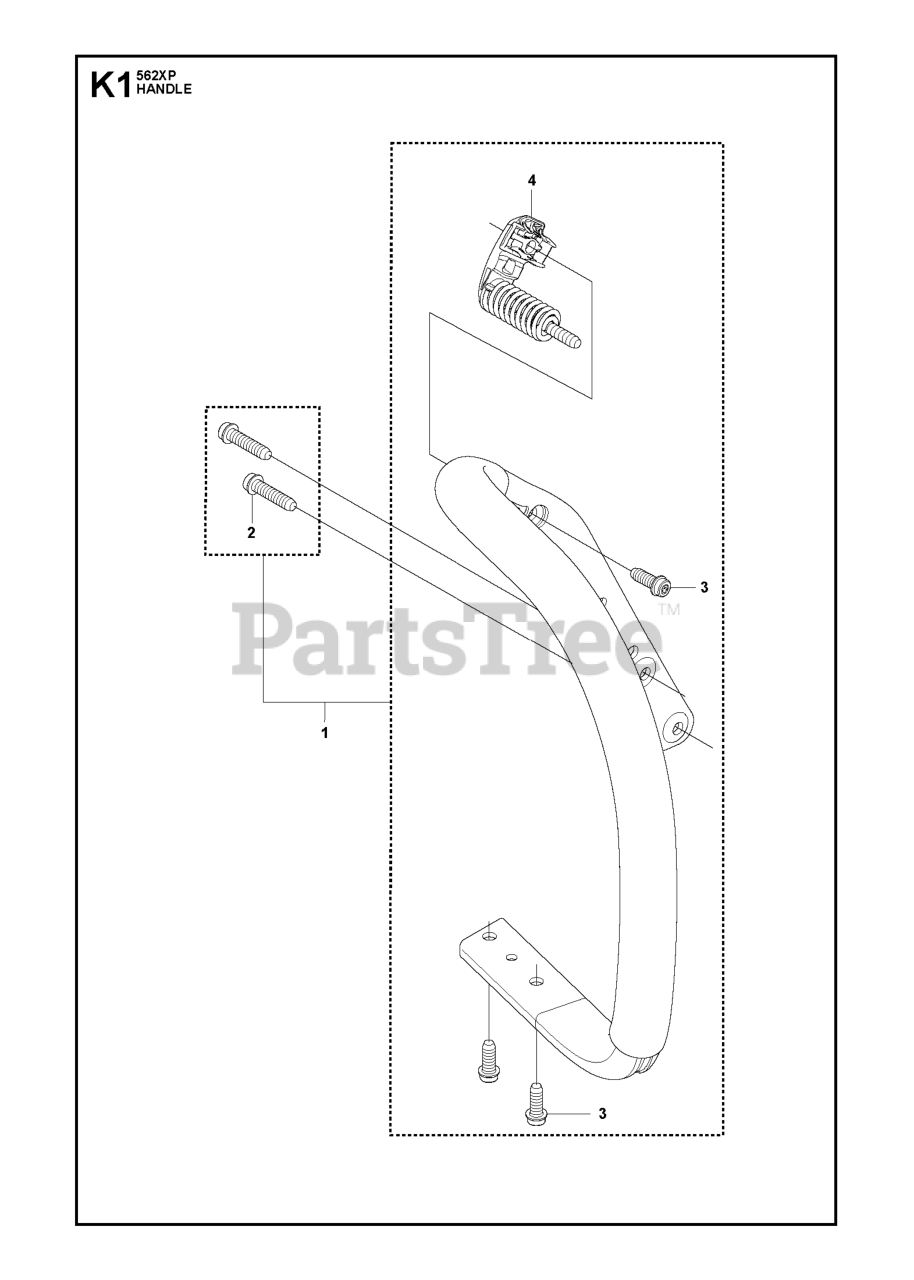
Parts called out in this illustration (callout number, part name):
1	FRONT HANDLE
3	SCREW ITXSCFT PL6X16 T27 10.9
4	ANTIVIBRATION ELEMENT CYLINDER
